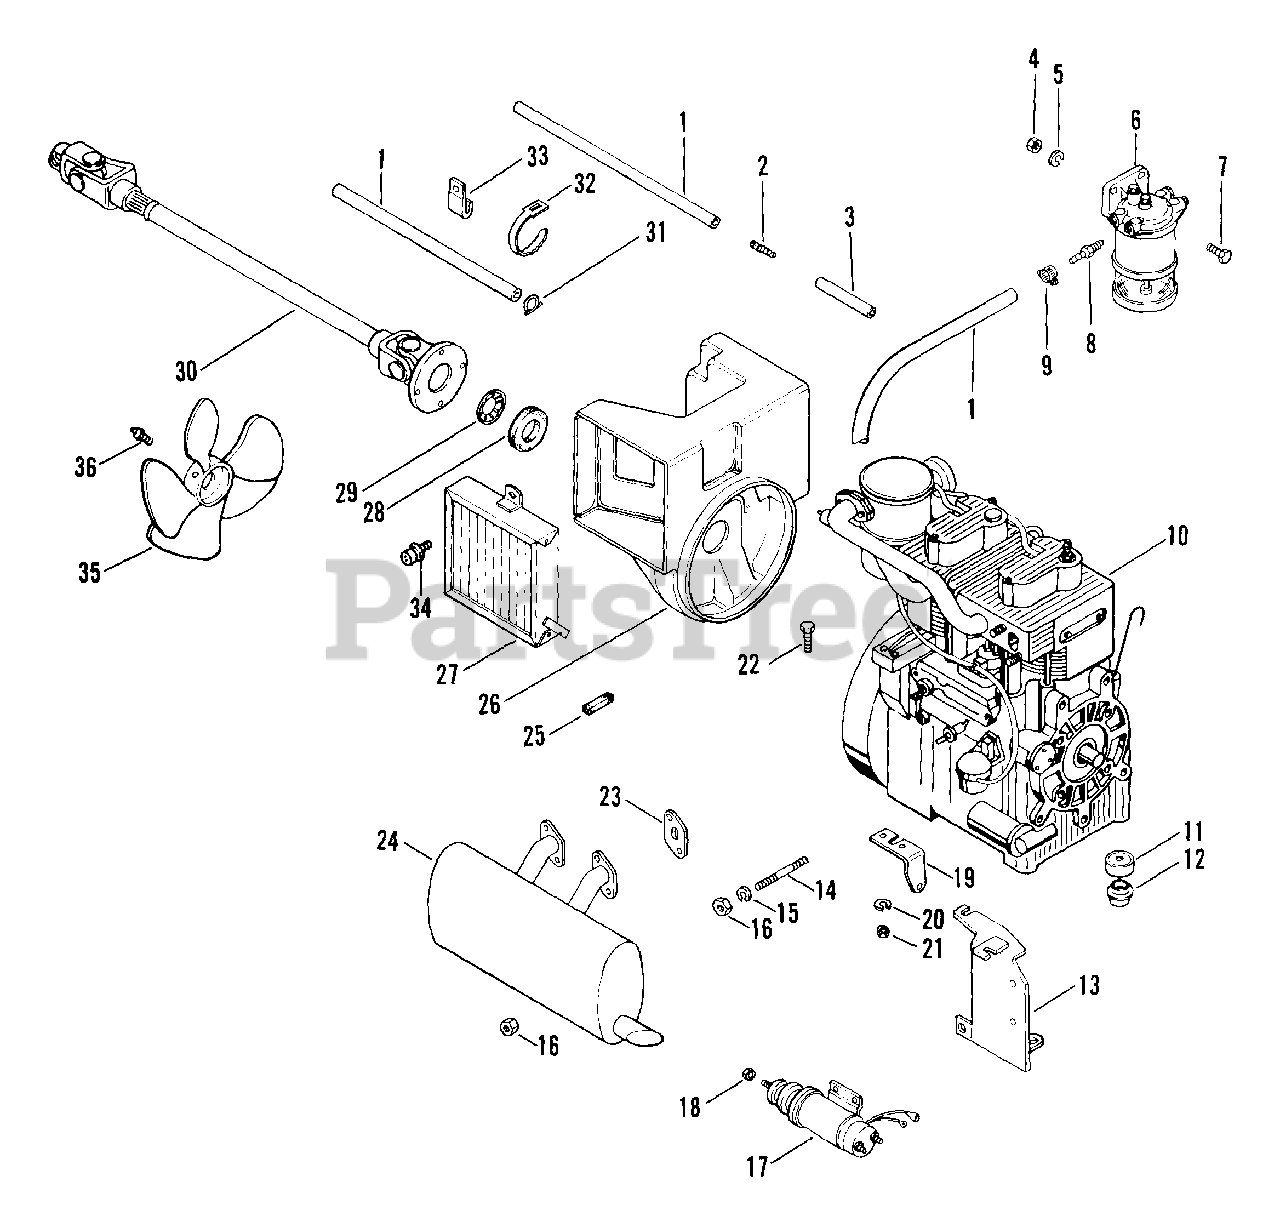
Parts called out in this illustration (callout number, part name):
1	FUEL LINE 1/4 X 67"
2	REDUCER
3	FUEL LINE
4	NUT-HEX .375-16
5	WSHR-LK .375X.094 MED PL
6	FUEL FILTER
6	FILTER ELEMENT
7	BLT-HEX .38-16X1.00 PL
8	HOSE END FITTING
9	HOSE CLIP
10	Engine
10	ENGINE ASSEMBLY
10	ENGINE,DIESEL
11	TOP ISOLATION MOUNT
12	BOTTOM ISOLATION MOUNT
13	SOLENOID BRKT WELD'T
14	STUD, M8-1.25X3.62" YWZC
15	WSHR-LK .312X.097 PL HVY
16	NUT M (ND)
17	SOLENOID
18	NUT M (ND)
19	THROTTLE CABLE ANCHOR
20	WSHR-LK .313X.078 PL MED
21	NUT-HEX .312-18
22	BLT-HEX .31-18X1.75 PL GR2
23	MUFFLER GASKET
24	MUFFLER
25	1 INCH OF 009103
26	AIR DUCT
27	AIR FILTER
28	SEALING WASHER
29	PUSH NUT, 1.00
30	DRIVE SHAFT
31	CLAMP-HOSE WIR.490/.510X.092#8
32	TIE DOWN
33	J-CLAMP
36	ZERK FITTING
